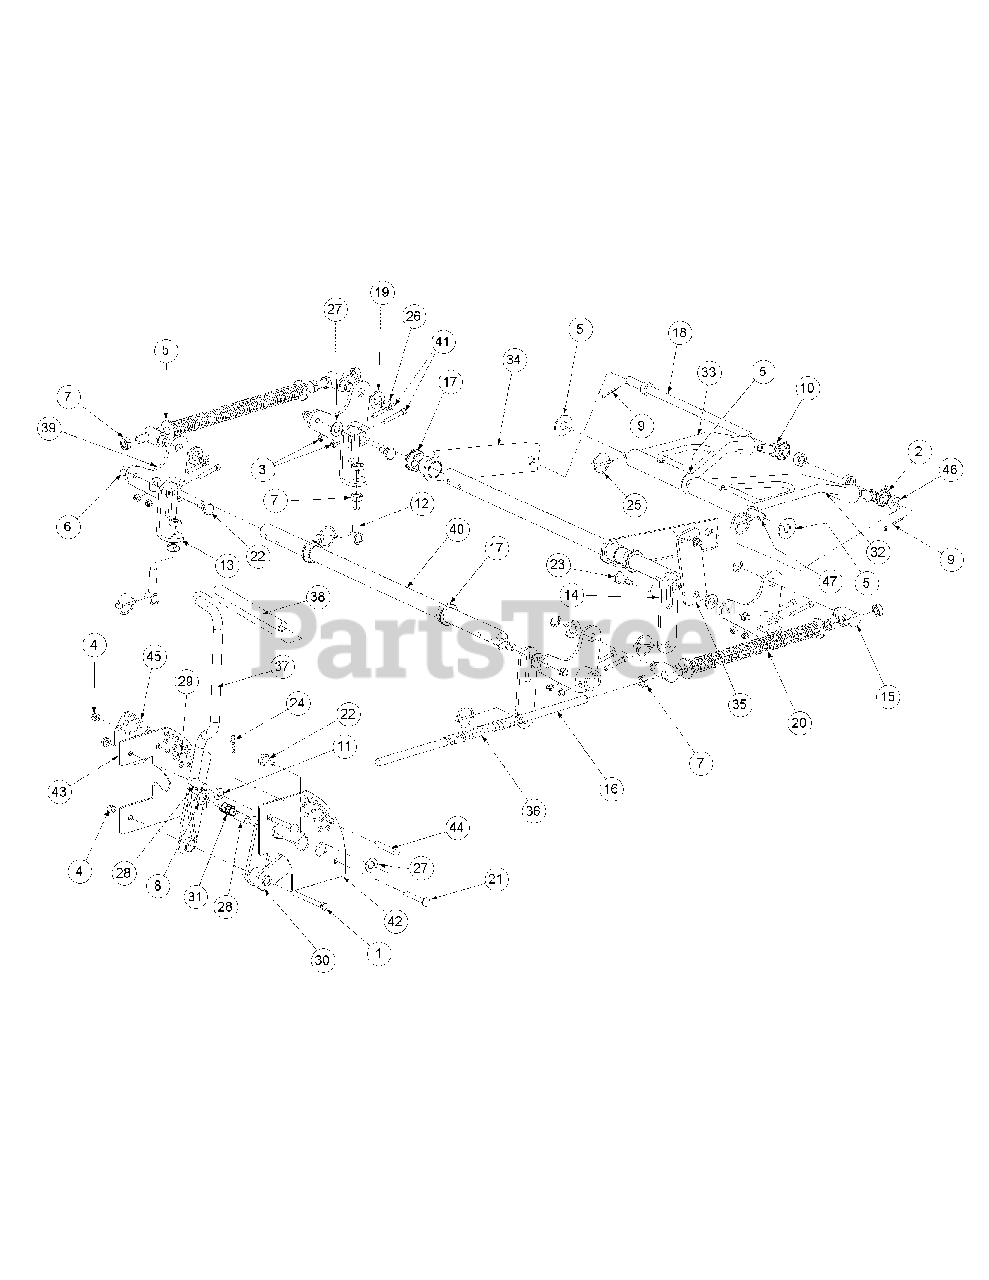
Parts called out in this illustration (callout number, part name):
1	Hex Cap Screw, 3/8-16, 3.75
2	Rod End, Male
3	Nut, 5/16-18, Nylock
4	Nylock Insert Lock Nut, 3/8-16
5	Flat Washer, 5/8
6	Hex Nut, Flange Lock, 3/8-16
7	Jam Nut, 5/8-11
8	Flat Washer, .06, .776, 1.25
9	Cotter Pin, 3/16 x 1-1
10	Jam Nut, 5/8-18
11	Idler Washer
12	Eye Bolt, 5/8ID
13	Eye Bolt Mount Link, 5/8 ID
14	Deck Link
15	Ferule Lift
16	Lift Connector Rod
17	Hex Flange Bearing, 1.25 ID
18	Front Lift Link, Rod Mount
19	Spacer, .812 ID x .268 Lg.
20	Lift Compression Spring
21	Carriage Bolt, 3/8-16, 2.75
22	Shoulder Screw, 0.625 OD x .437 Lg.
23	Shoulder Screw, 0.625 OD x .830 Lg.
24	Cotter Pin, .148 x 3.00
25	Linch Pin, 3/16 Dia.
26	E Clip, 3/4 Dia.
27	Nylon Flat Washer, 5/8
28	Spacer, .39 ID x .63 OD x 1.442
29	Shoulder Screw, .50 OD x 0.27
30	Lift Pivot Assembly
31	Lift Handle Spring
32	Bearing Lift Brace Assembly, Right Hand
33	Bearing Lift Brace Assembly, Left Hand
34	Front Frame Strut Assembly
35	Lift Link Adjustment
36	Hose, 5/8 ID 13/16 OD, 8" LG
37	Lift Handle Assembly
38	Lift Handle Grip
39	Bellecrank Weldment Assembly
40	Deck Lift Shaft
41	Socket Head CapScrew, 5/16-18 x 2
42	Outer Lift Index Plate
43	Inner Lift Index Plate
44	Clevis Pin, .438 Dia. x 2.625 Lg.
45	Decal Height Indicator
46	Spacer, .630 ID x 1.06 OD x .440
47	Lift Link Rod
